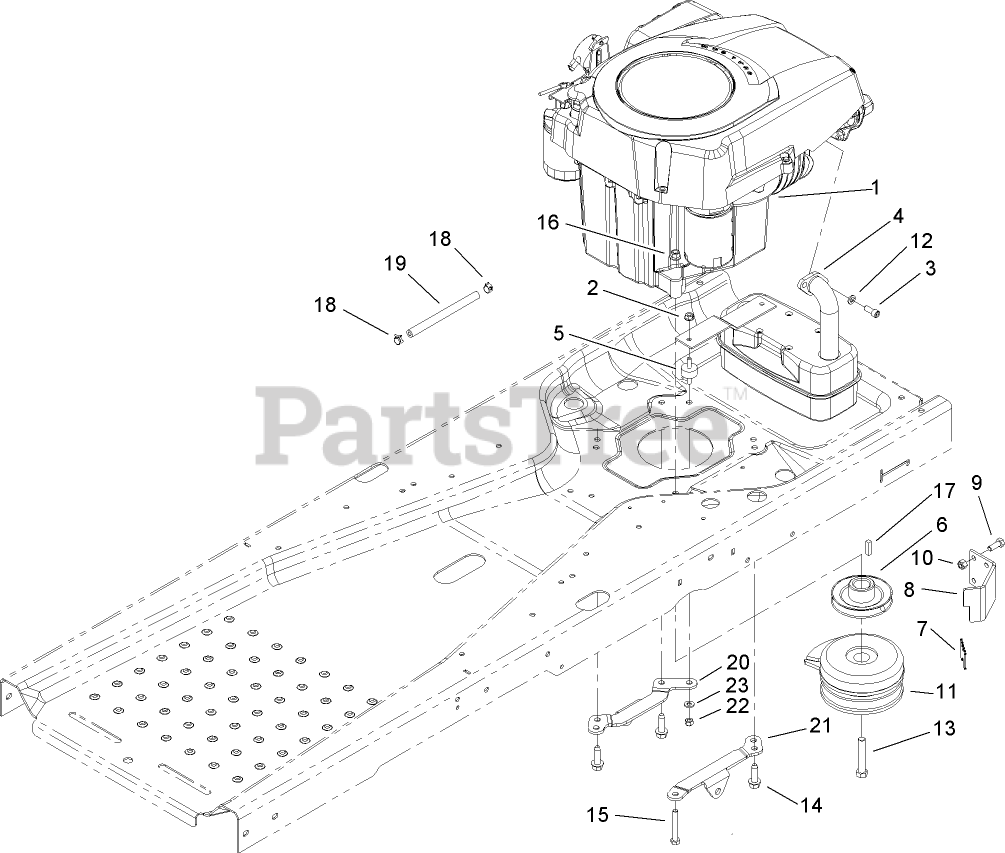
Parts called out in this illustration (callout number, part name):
1	Loose Parts Package
2	NUT-HF
3	SCREW-HSH
5	ISOLATOR
8	STOP-CLUTCH
9	SCREW-HH
10	NUT-LOCK, NI
11	CLUTCH-ELECTRIC
12	WASHER-LOCK
13	SCREW-HH
14	SCREW-THD
15	SCREW-HH
16	NUT-LOCK, NI
18	CLAMP-HOSE
19	HOSE-FUEL
20	SUPPORT-HYDRO, RH
21	SUPPORT-HYDRO, LH
22	NUT-LOCK, NI
23	WASHER-FLAT
